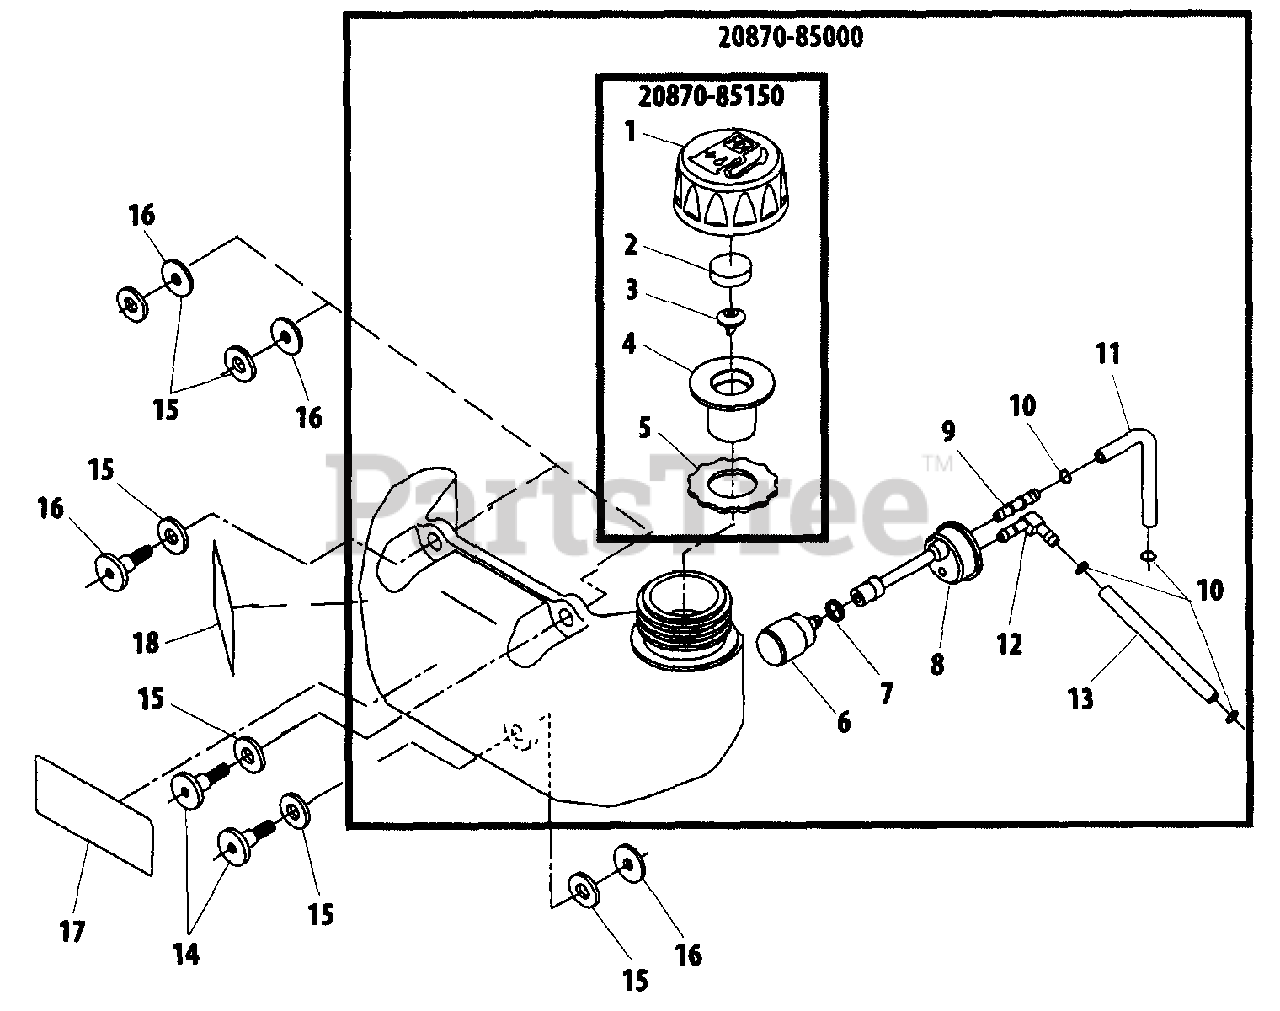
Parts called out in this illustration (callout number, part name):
1	CAP, FUEL
2	PACKING
3	VENT
4	HOLDER, VENT
5	GASKET, FUEL CAP
6	FILTER, FUEL 125-528
7	CLIP
8	GROMMET, FUEL WITH PIPE
9	CONNECTOR, PIPE
10	CLIP Ø6
11	PIPE, FUEL
12	CONNECTOR, PIPE
13	PIPE, RETURN
14	BOLT
15	WASHER
16	WASHER
17	LABEL - CAUTION
18	LABEL
20870-85000	FUEL TANK ASSY
20870-85150	CAP ASSY
